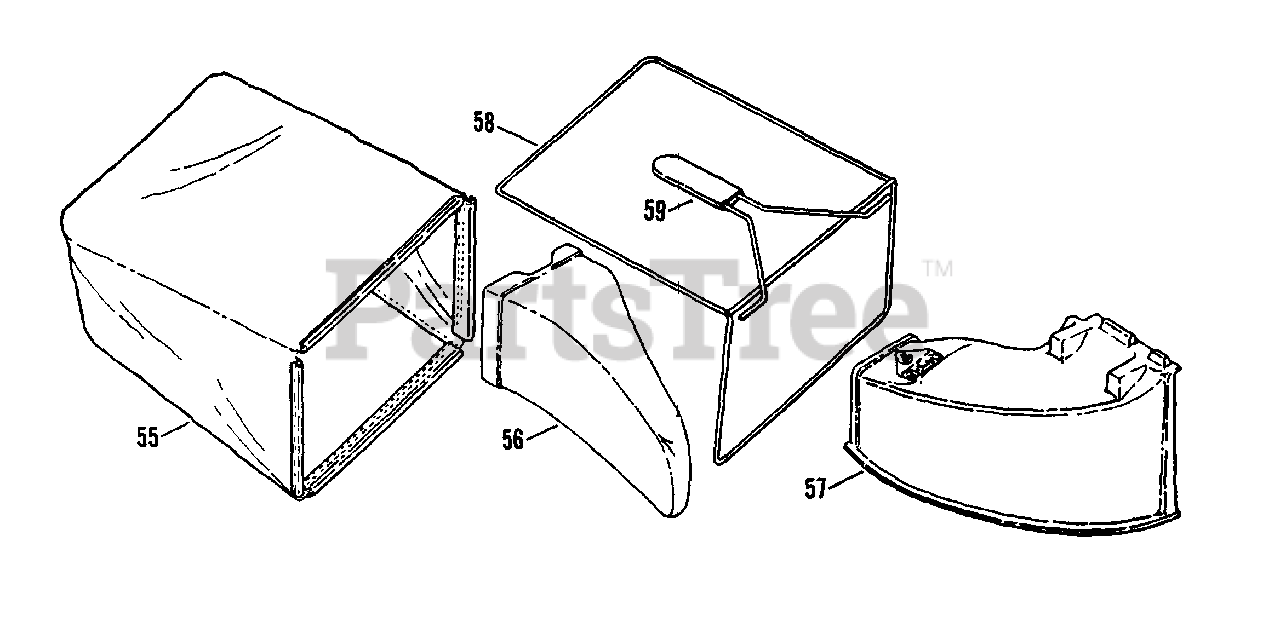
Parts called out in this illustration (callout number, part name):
55	ASSEMBLY, Catcher
56	PLUG, Mulching
57	CHUTE, Side Discharge
58	ASSEMBLY, Catcher Frame
59	GRIP, Catcher Frame
